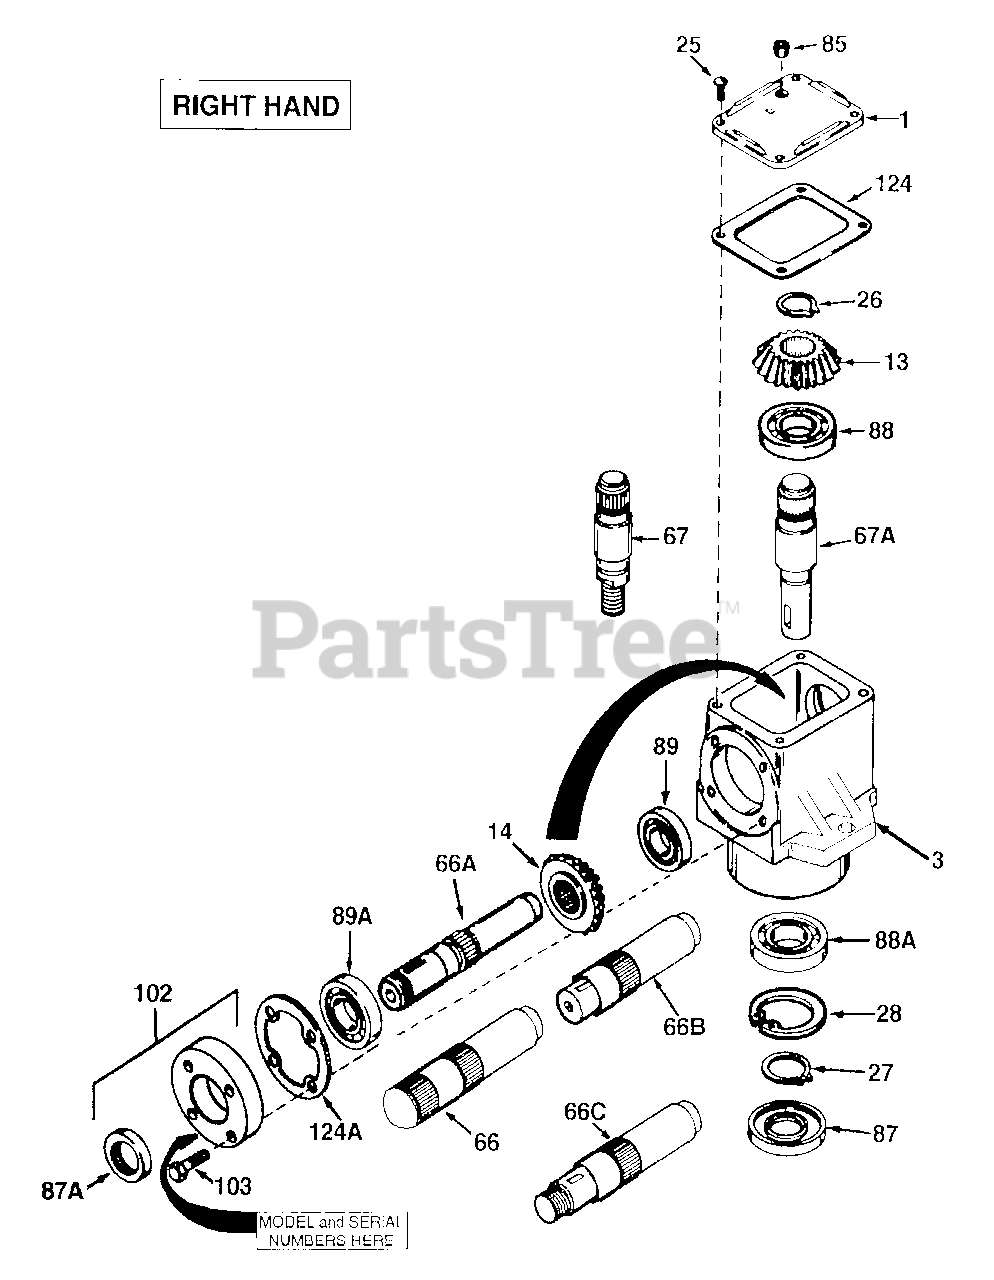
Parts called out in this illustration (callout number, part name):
1	Right Hand Cover
3	Right Angle Drive Housing
13	Miter Gear (17 teeth-steel)
14	Miter Gear (17 teeth)(7/8" long)
25	Screw, 10-24 x 1/2"
26	Retaining Ring
27	Retaining Ring
66C	Input Shaft (5.570" long)
67A	Output Shaft (4.259" long)
85	Pipe Plug, 1/8-27 Headless
87	Oil Seal 7/8"
87A	Oil Seal 7/8"
88	Ball Bearing
88A	Ball Bearing
89	Ball Bearing
102	Retainer Cap
103	Bolt, 1/4-20 x 7/8"
124	Cover Gasket
